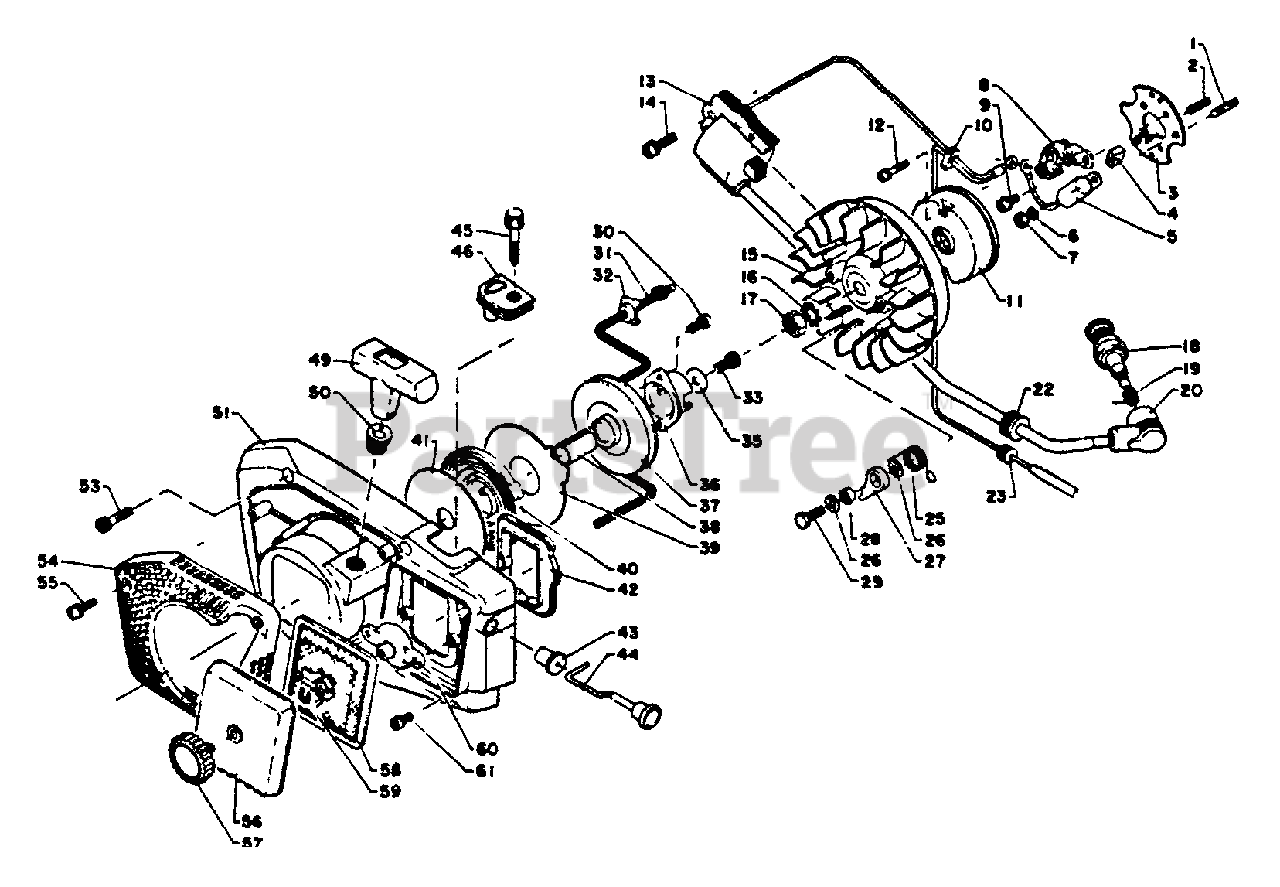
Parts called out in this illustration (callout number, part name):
1	STUD
2	STUD
3	PLATE, STATOR
4	OILER
5	CONDENSER
6	WASHER, SPRING 4 MM
8	CONTACT POINT SET
9	SCREW 4×8
10	RUBBER BUSH (B)
11	COVER, BREAKER
12	SCREW 3×18
13	COIL, IGNITION
14	SCREW 5×20
15	FLYWHEEL
18	SPARK PLUG - BM6A
19	TERMINAL, SPARK PLUG
20	CAP, SPARK PLUG
22	GROMMET
23	GROMMET
26	WASHER, FLAT 5.5×10×0.8
27	PAWL, STARTER
29	BOLT 5×18
30	SCREW - 4×10
31	ROPE, STARTER
32	RETAINER, ROPE
33	BOLT 5×14
35	WASHER 5.2×16×1.0
36	PAWL CATCHER
37	REEL, ROPE
39	PLATE, STARTER
40	SPRING, RECOIL
41	PLATE, STARTER
42	PACKING
43	GROMMET
44	ROD, CHOKE
45	SCREW, IDLE ADJUST
46	GROMMET
50	GUIDE, ROPE
51	CASE, STARTER
53	BOLT 5×20
54	FILTER, DEBRIS
55	SCREW 4×12
56	COVER, AIR FILTER
57	THUMBSCREW
58	FILTER, AIR
59	E-RING 4
60	PLATE, PREVENT
61	SCREW 4×8
